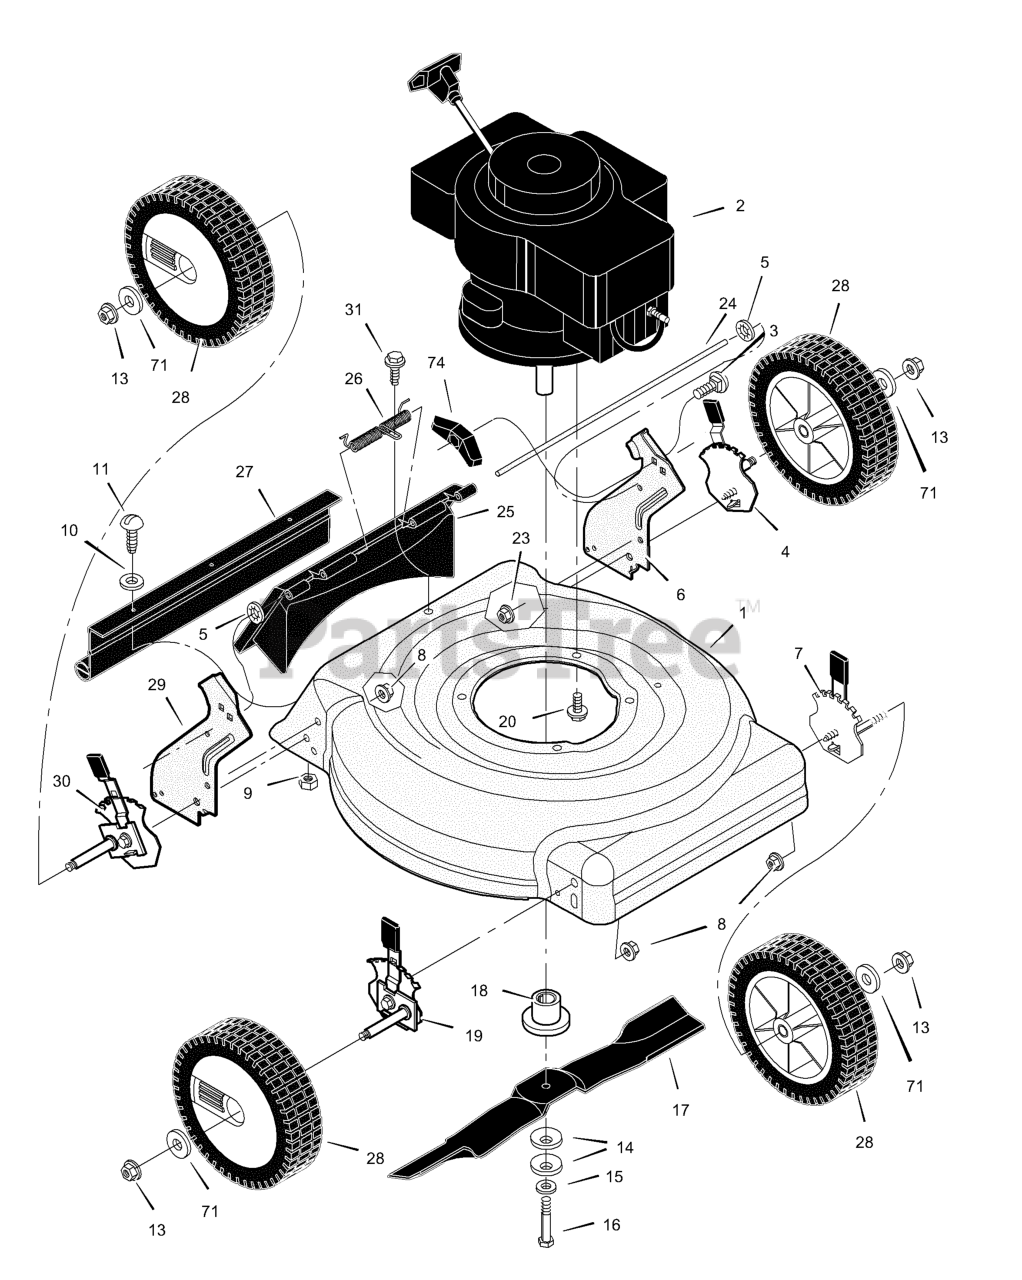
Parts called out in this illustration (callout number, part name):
1	Housing
2	Engine
4	Adjuster, Left Rear Height
5	Nut, Push
6	Bracket, Left Handle
7	Adjuster, Left Front Height
8	Nut, Flange
9	Nut, Hex
13	Nut, Flange
14	Washer, Belleville
18	Adapter, Blade
19	Adjuster, Right Front Height
20	Bolt, Engine
23	Nut, Flange
24	Rod, Pivot
25	Door, Rear (Black)
26	Spring
27	Guard, Rear
28	Wheel & Tire
29	Bracket, Right Handle
30	Adjuster, Right Rear Height
